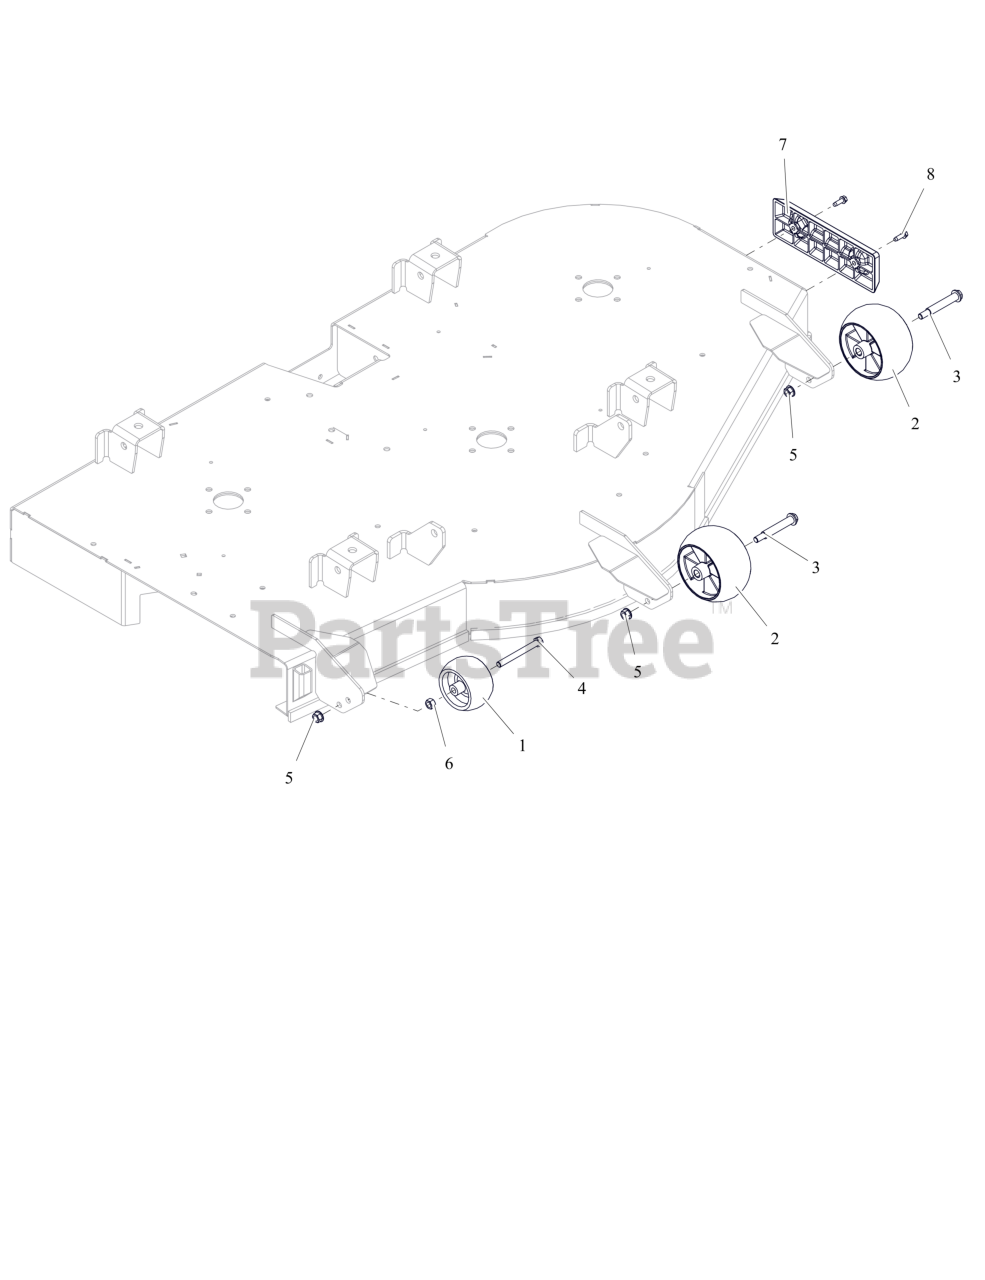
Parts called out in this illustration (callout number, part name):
2	ANTI-SCALP WHEEL - 5X OS
3	BLT-SHLDR .38-16X2.50 HWH G5
4	BLT, HEX .38-16X3.50 G5 ZCC
5	NUT-LK-CTR-FLG .375-16 GF ZCC
6	NUT-STD .375-16 G2 ZCC
7	BUMPER, DECK
8	SCR,TAP .25-20X.75 HWH TR ZCC
